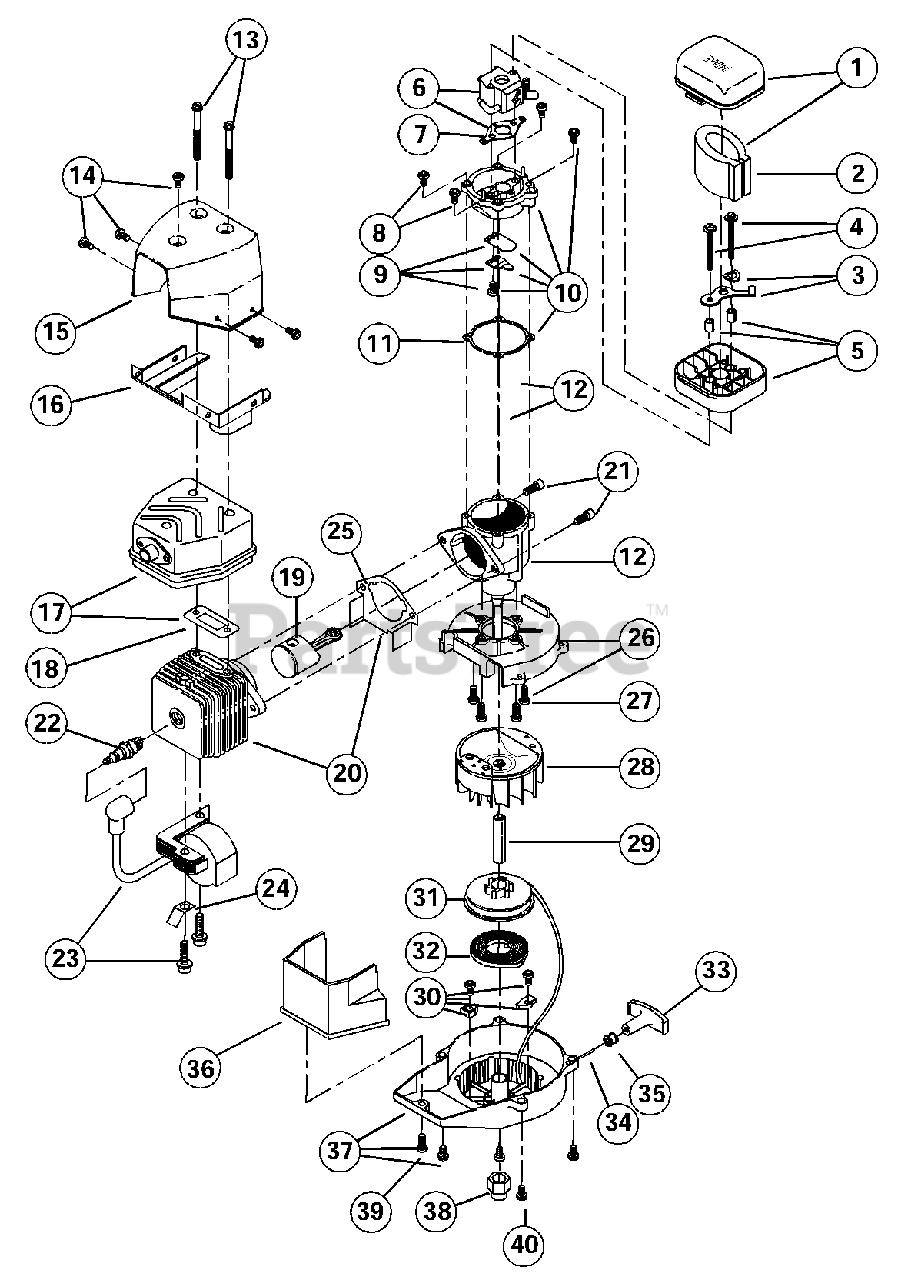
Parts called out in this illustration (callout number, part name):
1	Air Cleaner Cover Assembly
2	Air Cleaner Filter
3	Choke Lever Assembly
4	Mounting Bolt Assembly
5	Air Cleaner Base
6	Carburetor Assembly
7	Carburetor Gasket (10 pack)
8	Reed Plate Mounting Screw
9	Reed Assembly
10	Complete Reed Plate Assembly
11	Reed Plate Gasket
12	Crankcase Service Assembly
13	Muffler Mounting Bolt
14	Mounting Screw Assembly
15	Upper Heat Shield
16	Lower Heat Shield
17	Muffler Assembly
18	Exhaust Gasket (10 pack)
19	Piston and Rod Assembly
20	Cylinder Assembly
21	Cylinder Bolt
22	Spark Plug
23	Module Assembly
24	Ground Tab
25	Cylinder Gasket
26	Shroud Assembly
27	Shroud Screw
28	Flywheel Assembly
30	Pulley Retainer Assembly
31	Recoil Pulley Assembly
32	Recoil Spring
33	Pull Handle
35	Rope Guide
36	Shroud Extension
37	Starter Housing Assembly
38	Crankshaft Extension
39	Shroud Extension Screw
40	Housing Screw
